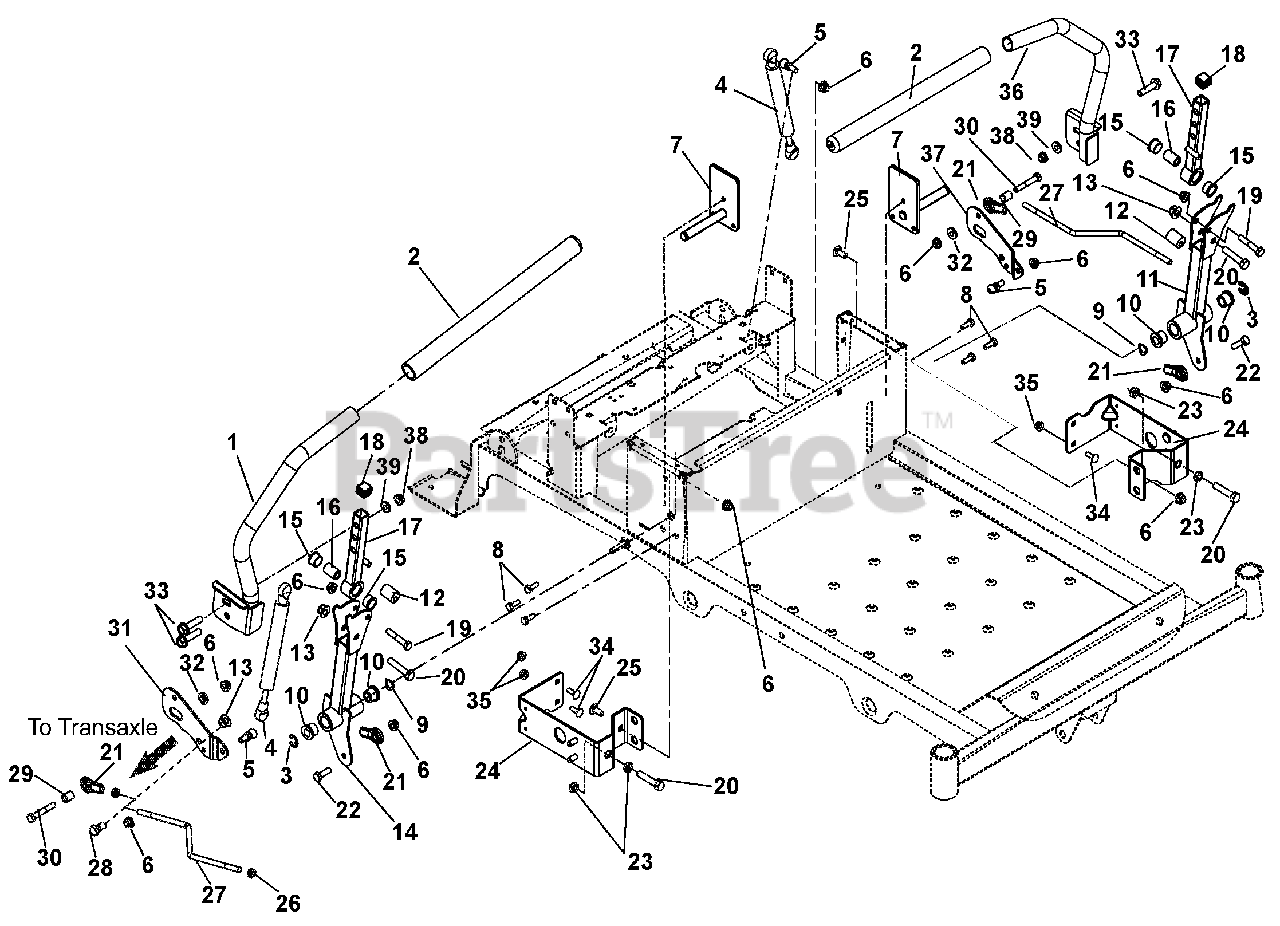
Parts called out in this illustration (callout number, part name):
1	WMT, STEERING HANDLE
2	GRIP, HANDLEBAR 15" FOAM
3	RG-RTNG-EXT .500X.042 (E)
4	DAMPER, STABILUS
5	STUD- BALL
6	@NUT-LK-NYL-FLG .31-18 YWZC
7	WMT, STEERING SHAFT
8	SCR-TAP .25-20X.50 HWH TR YWZ
9	WSHR-WAVE .50X.75X.015 .13FRHT
10	BSHG-FLG .500X.750X.625X.937
11	WMT, LOWER CONTROL ARM
12	BSHG, ECCENTRIC .328X.750X.970
13	@NUT-LK-NYL-FLG .38-16 YWZC
14	WMT, LOWER CONTROL RH
15	BSHG-FLG, .625X.75X.450X.875
16	SPACER, .375X.625X.970 (PM)
17	WMT, UPPER CONTROL ARM
18	CAP PLUG, SQ 3/4-14-20 RIBBED
19	@BLT-HEX .31-18X1.75 GR5 YWZC
20	BLT-HEX .375-16X1.750 FTD YWZC
21	ALIGNABALL, 5/16 RH THREAD
22	@BLT-HEX .31-18X1.00 GR5 YWZC
23	NUT-HEX-JAM .375-16 YWZC
24	WMT, STEERING STOP
25	@BLT-RHDSSQNK .31-18X.75 G5YZ
26	NUT-JAM .31-24 YWZC
27	WIREFORM, STEERING LINK
28	@BLT-HEX .38-16X.75 GR5 YWZC
29	SPACER, .328X.500X.625
30	@BLT-HEX .31-18X2.00 GR5 YWZC
31	PLATE, DAMPER RH
32	BSHG-FLG .316X.430X.225X.750
33	BLT-SERHFWH .375-16X1.25 YWZC
34	@BLT-RDHDSQNK .25-20X.75 G5YZ
35	@NUT-LK-NYL-FLG .25-20 YWZC
36	WMT, STEERING HANDLE LH
37	PLATE, DAMPER (LH)
38	@NUT-LK-CTR-JAM .375-16 YWZC
39	@WSHR-FL-STL.406X.812X.065 YWZ
